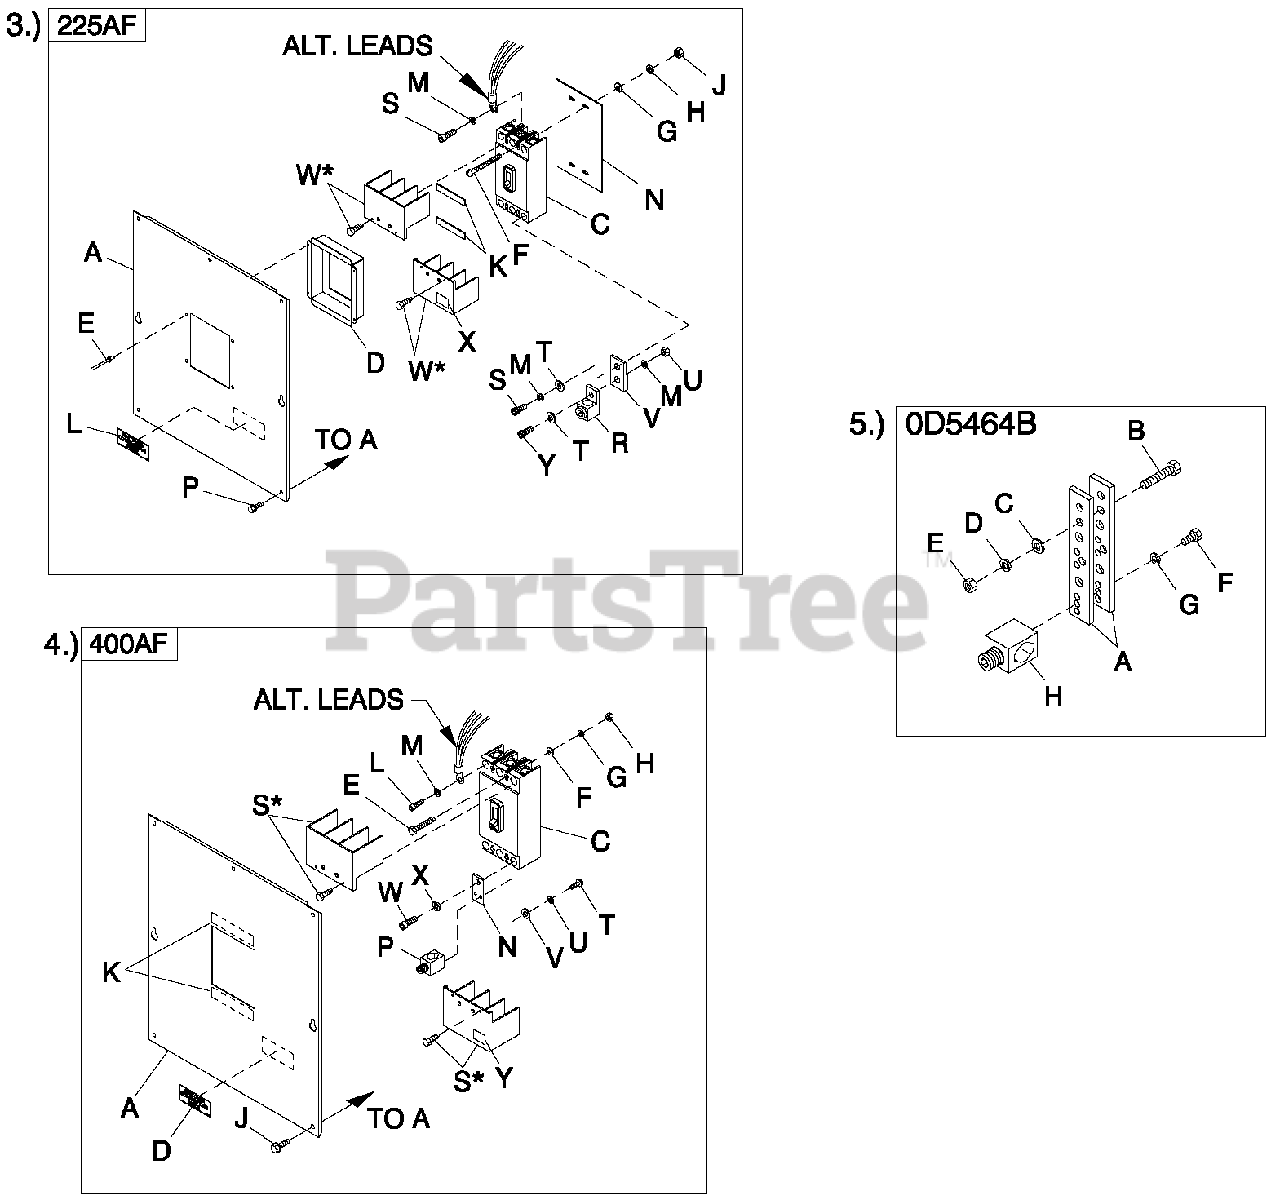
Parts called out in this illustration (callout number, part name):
A	COVER CBC5 225AF
C	CIRCUIT BREAKERS 200A FRAME
D	COVER CB DISH 225AF
E	RIVET POP .125 X .275 SS
F	SCREW RHM #8-32X3-1/4
G	WASHER FLAT #8 ZINC
H	WASHER LOCK #8-M4
J	NUT HEX #8-32 STEEL
K	TAPE ELEC 1/2 FOAM
L	DECAL CUSTOMER CONNECT INSIDE
M	WASHER LOCK M8-5/16
N	INSULATOR CB225AF
P	SCREW THF M6-1 X 16 N WA Z/JS
R	LUG SLDLSS 300 MCM-6 AL/CU
S	SCREW SHC M 8 -1.25X20G 8
T	WASHER FLAT 5/16-M8 ZINC
U	NUT HEX M8-1.25G8 CLEAR ZINC
V	BUS BAR 200A LUG ADAPTOR
W	TERMINAL COVER CB
X	DECAL TERMINAL SHOCK HZD BI
Y	SCREW SHC M8-1.25 X 25 G12.9
A	COVER CBC5 400AF
C	CIRCUIT BREAKERS 400A FRAME
D	DECAL CUSTOMER CONNECT INSIDE
E	SCREW RHM 1 0 -3 2X4
F	WASHER FLAT #10 ZINC
G	WASHER LOCK #10
H	NUT HEX #10-32 STEEL
J	SC RE W THF M6-1 X 16 N WA Z/JS
L	SCREW SHC M10-1.5X 25 G12.9
M	WASHER LOCK M10
N	BUS BAR CB ADAPTER 225-400 A
P	LUG SLDLSS 600/250-1/0 X 1/4-28
R	WASHER FLAT 3/8-M10 ZINC
S	TERM COVER CB
T	SCREW HHC 1/4-28 X 1/2 G5
U	WASHER LOCK M6-1/4
V	WASHER FLAT 1/4-M6 ZINC
W	SCREW SHC M10-1.5X 25 G12.9
X	WASHER LOCK M10
Y	DECAL TERMINAL SHOCK HZD BI
A	COVER CBC5 800AF
C	CIRCUIT BREAKERS 800A FRAME
D	INSULATOR CB800AF
E	SCREW RHM 1/4-20X3-1/2
F	WASHER FLAT 1/4-M6 ZINC
G	WASHER LOCK M6-1/4
H	NUT HEX 1/4-20 STEEL
J	SCREW THF M6-1X16 N W AZ/JS
L	SCREW SHC M10-1.50 X 40 G12.9
M	WASHER FLAT 3/8-M10 ZINC
N	WASHER LOCK 3/8
P	NUT HEX M10-1.5 G8YEL CHR
R	LUG SLDLSS 3/0-400X3 MCM AL/CU
S	SCREW SHC M6-1.0X 50 G8.8
T	DECAL CUSTOMER CONNECT INSIDE
U	TERM COVER VITZROTECH 400AF CB
V	DECAL TERMINAL SHOCK HZD BI
W	WASHER LOCK M6-1/4
A	BUS BAR NEUTRAL BLOCK 390
B	SCREW HHC M8-1.25 X 45 G8.8 FT
C	WASHER FLAT 5/16-M8 ZINC
D	WASHER LOCK M8-5/16
E	NUT HEX M8-1.25 G8 YEL CHR
F	SCREW HHC 1/4-28 X 3/4 G5
H	LUG SLDLSS 600/250-1/0X1/4-28
